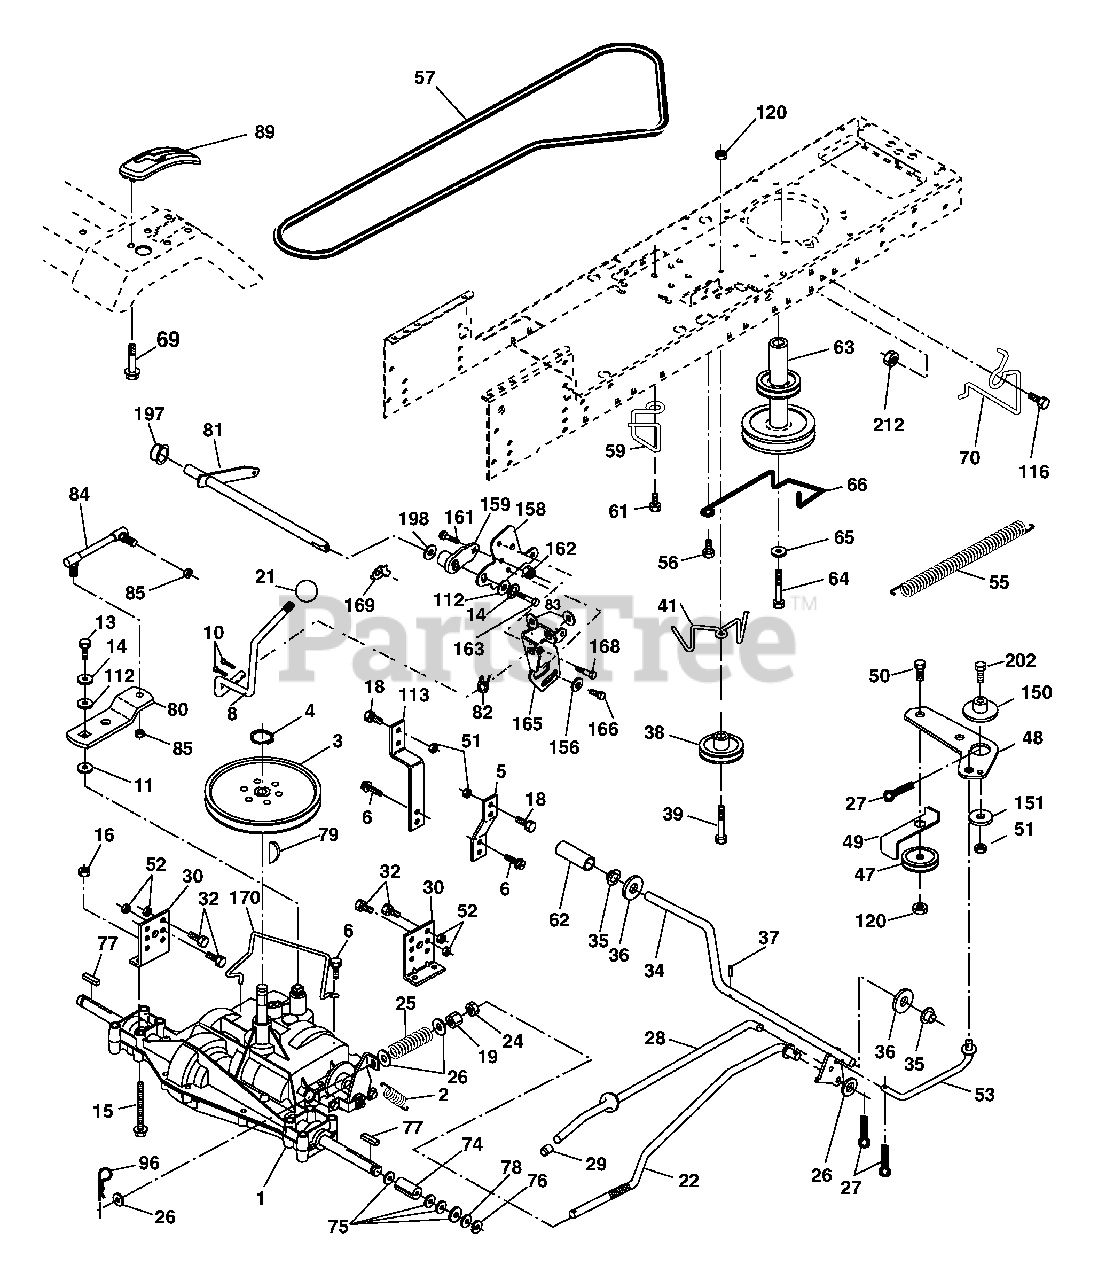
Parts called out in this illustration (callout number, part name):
2	Spring Return Brake T/a Zinc
3	Pulley Transaxle 18" tires
4	Ring Retainer # 5100-62
5	Strap Torque 30 Degrees
6	Screw 5/16-18 X 3/4
8	Rod Shift Fender Adjust Lt
10	Pin Cotter 1/8 X 1 Cad
11	Washer Plate Shf 388 Sq Hole
13	Bolt 1/4-28 Unf Gr. 8 W/Patch
14	Washer Lock Hvy Helical
15	Bolt Hex FLGHD 5/16-18 Gr. 5
16	Nut Lock Hex w/ins 5/16-18
18	Bolt, Fin Hex 3/8-16 unc x 1 Gr. 5
19	Nut Lock 3/8-16 Unc
21	Knob
22	Rod Brake Blk Zinc 26 840
24	Nut Hex Jam 3/8-16 unc
25	Spring Rod Brake 2 00 Zinc
26	Washer 13/32 x 13/16 x 16 Ga.
27	Pin Cotter 1/8 x 3/4 Cad
28	Rod Brake Parking LT/YT
29	Cap Brake Parking
30	Bracket Mtg Transaxle
32	Bolt Hex Hd 5/16-18 unc x 3/4
34	Shaft Asm Pedal Foot
35	Bearing Nylon Blk 629 Id
36	Washer 21/32 x 1 x 16 Ga.
37	Pin Roll 3/16 X 1"
38	Pulley Composite Flat
39	Bolt RDHD 3/8-16 unc x 2-3/4 Gr. 5
41	Keeper Belt Flat Idler
47	Pulley Idler V Groove Plastic
48	Bellcrank Asm
49	Retainer Belt Style Spring
50	Bolt Carr. Sh. 3/8-16 x 1-1/2 Gr. 5
51	Nut Crownlock 3/8-16 unc
52	Nut Crownlock 5/16-18 unc
53	Link Clutch
55	Spring Return Clutch 6 75
56	Screw 3/8-16 x 1-1/4
57	V-Belt Ground Drive 95 25
59	Keeper Belt Span Ctr
61	Screw 3/8-16 x .875
62	Cover Pedal Blk Round
63	Engine Pulley
64	Bolt Hex
65	Washer Lock Hvy Hlcl Spr 7/16
66	Keeper Belt Engine Foolproof
69	Screw Hex wsh Hi Lo 1/4 x 1/2 unc
70	Guide Belt Mower Drive RH
74	Spacer Axle
75	Washer 25/32 x 1 1/4 x 16 Ga.
76	E-ring #5133-75
77	Key Square 2 0 x 1845/ 1865
78	Washer 25/32 x 1-5/8 x 16 Ga.
79	Key Woodruff #9 3/16 x 3/4
80	Arm Shift
81	Shaft Asm Cross Tapered PMST/ 20
82	Spring Torsion T/a
83	Washer 17/32 x 3/4 x 16 Ga.
84	Link Transaxle PMST/18" Zinc
85	Nut Lock Center 1/4 - 28 FNTHD
89	Console Shift STLT
96	Retainer Spring 1"
112	Washer 9/32 x 3/4 x 10 Ga.
113	Strap Torque LT
116	Bolt Rdhd Sq Neck 3/8-16 x 1
120	Nut Lock Flg. 3/8-16 unc
150	Spacer Retainer
151	Washer 13/32 x 2 x 10
156	Washer Srrted 5/16ID x 1.125
158	Bracket Shift Mount
159	Hub Tapered Flange Shift Lt
161	Bolt Rdhd Sqnk 1/4-20 x 3/4
162	Nut Crownlock 1/4-20 unc
163	Bolt Hex Fin 1/4-20 unc x 1 Gr. 5
165	Bracket Pivot Lever
166	Screw 5/16-18 x 5/8
168	Bolt Shoulder 5/16-18 x .561
169	Plate Fastening
170	Keeper Belt Transaxle Gear
197	Nyliner Snap-In
198	Washer Nyliner
202	Bolt Rd Hd 3/8-16 unc x 1-3/4 Gr.
212	Nut Hexflange Lock
